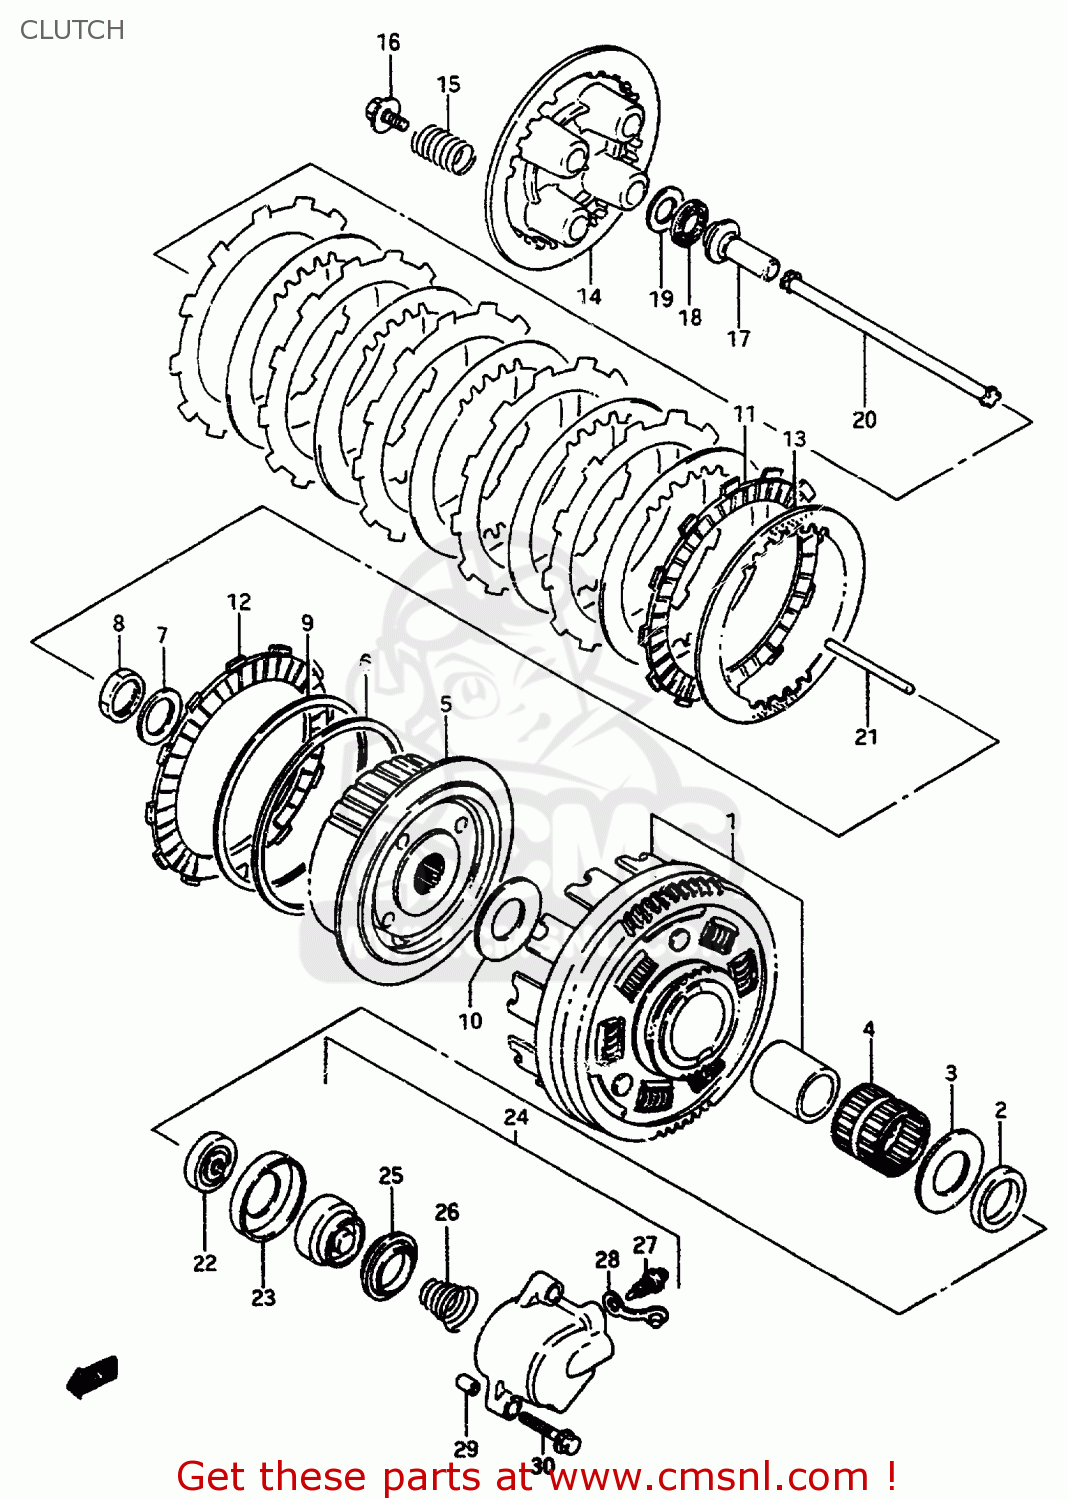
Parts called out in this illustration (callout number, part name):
1	GEAR ASSY,PRIMARY(NT:71)
2	SPACER(25X38X6.5)
3	WASHER(25X50X2.5)
4	BEARING(35X40X35.8)
5	HUB COMP,CLUTCH SLEEVE
6	SEAT,WAVE WASHER(T:1.4)
7	WASHER
8	NUT
9	WASHER
10	WASHER(25X50X2.5)
11	PLATE,CLUTCH DRIVE (NAS)
12	PLATE,CLUTCH DRIVE(T:3.5) (NAS)
13	PLATE,CLUTCH DRIVEN(T:1.6) (NAS)
14	DISC,CLUTCH PRESSURE
15	SPRING
16	BOLT
17	PIECE,CLUTCH PUSH
18	BEARING(15X28X2)
19	WASHER
20	ROD,CLUTCH
21	ROD,CLUTCH PUSH,L
22	SEAL,OIL(6X34X11)
23	RETAINER,CL PUSH ROD OIL SEAL
24	CYLINDER,CLUTCH RELEASE
25	CUP,CLUTCH CYLINDER
26	SPRING,CLUTCH CYLINDER
27	BLEEDER
28	CAP,BLEEDER
29	PIN
30	BOLT
